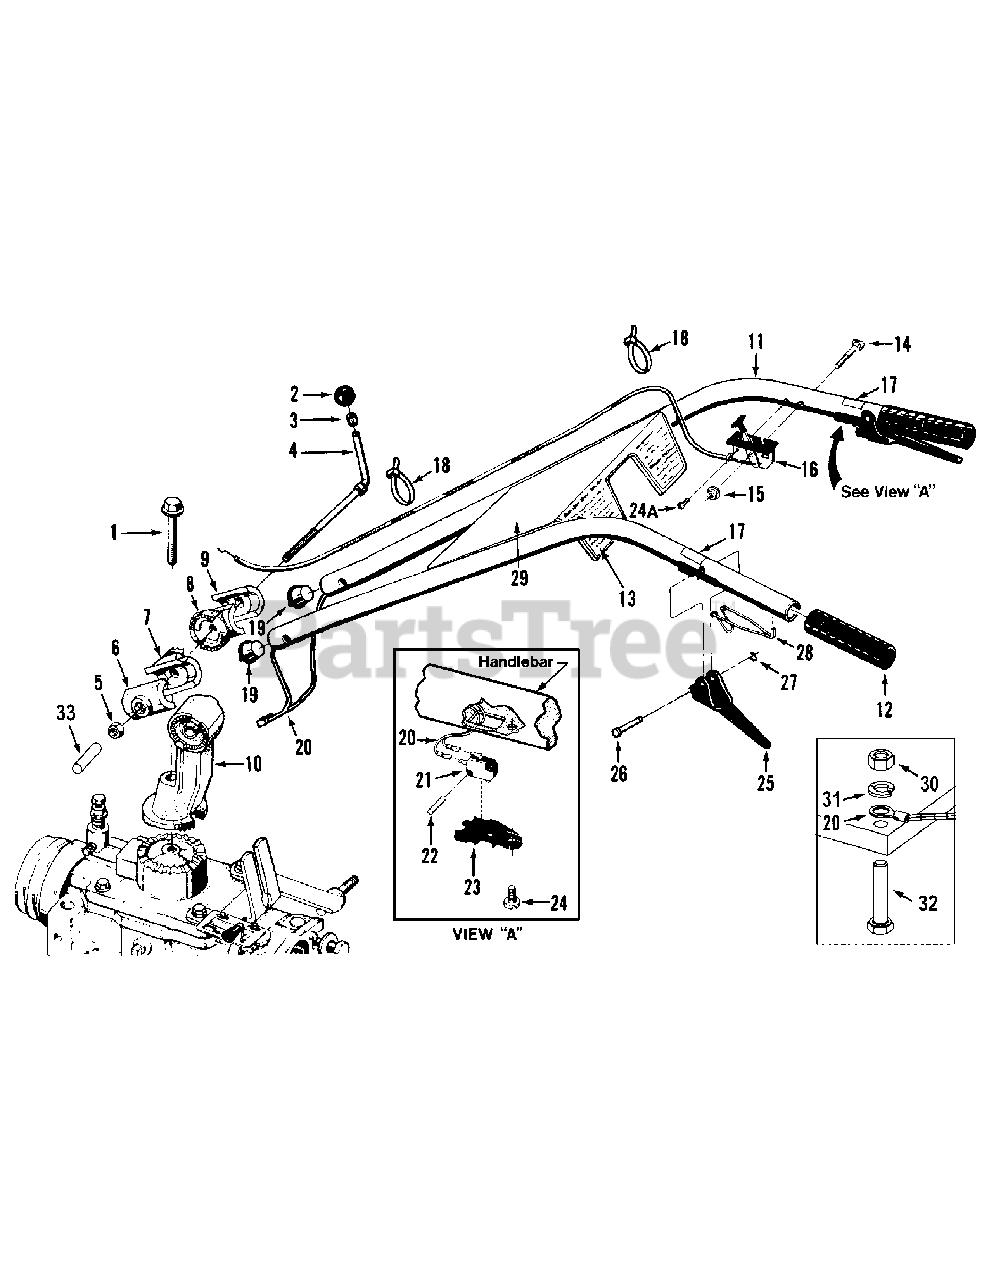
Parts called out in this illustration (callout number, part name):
1	Bolt-Hex hd., flanged self-locking Grade 5, 1/2-13 x 3-1/2"
2	Knob-handlebar height adjustment
3	Ring-retaining (tolerance right)
4	Stud-handlebar height adjustment
5	Nut-hex, 1/2"-13
6	Clamp-left, handlebar height adjustment
7	Ratchet-left, handlebar height adjustment
8	Ratchet-right, handlebar heght adjustment
9	Clamp-right, handlebar height adjustment
10	Base-handlebar mounting
12	Grip-handlebars
13	Decal-Control panel
14	Bolt-curved hd, GR5, 1/4-20 x 2"
15	Nut-hex, flanged self-locking, whiz lock, 1/4"-20
16	Throttle Control & Cable, 66"
17	Decal-Forward Interlock Lever
18	Tie-Plastic
19	Plug-wire harness retainer
20	Handlebar Wire Harness Ass'y.-forward interlock system
21	Handlebar Switch-forward interlock system
22	Lock Pin-handlebar switch
23	Switch Housing-handlebar switch
23	Switch Assembly (Incl. Refs. 21-23)
24	Screw-pan head, #10-16 x 1/2", thread-forming
24A	Screw-philips head, 10-32 x 1/2", thread-forming
26	Pivot Pin-forward interlock lever
27	Retaining Ring-kilp ring-forward interlock lever
28	Return Spring- fwd interlock lever
29	Label-Troy-Bilt Horse
29	Label-Troy-Bilt Horse "Big Red"
30	Nut-hex 5/16-18
31	Washer 5/16
32	HH Cap Screw 5/16-18 x 1.5
